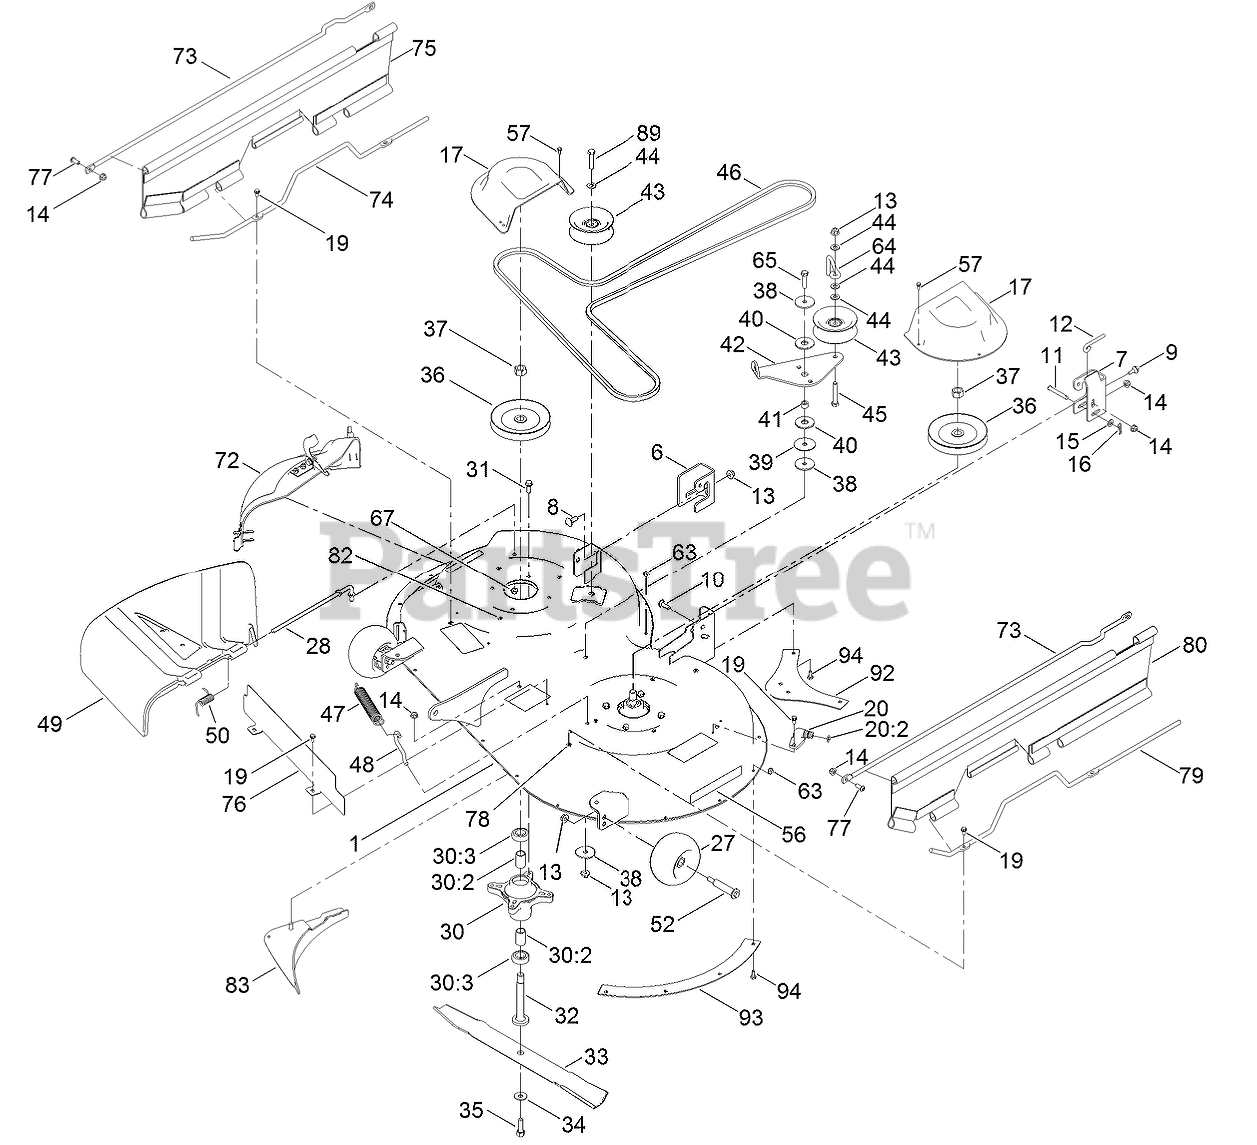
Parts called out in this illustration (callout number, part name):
1	42 INCH DECK AND DECAL ASM
6	BRACKET-HANGER, RH
7	BRACKET-HANGER, LH
8	BOLT-CARR
9	SCREW-SHOULDER,HWH
10	SCREW-CARR
11	PIN-CLEVIS
12	ROD-LEVEL, DECK
13	NUT-HF, NI
14	NUT-HF, NI
15	WASHER-PLAIN
16	PIN-COTTER
17	COVER-BELT
19	SCREW-HWH
20	FITTING-WASHOUT
20:2	O-RING
27	ROLLER-SCALP, ANTI
28	ROD-PIVOT
30	SPINDLE ASM
30:2	SPACER
30:3	BEARING-BALL
31	SCREW-TAPTITE
32	SHAFT-SPINDLE
33	BLADE-MULCH
34	WASHER-BELLEVILLE
35	SCREW-HH
36	PULLEY
37	NUT-HEX
38	WASHER-REBOUND
39	WASHER
40	WASHER-FRICTION, COMPOSITE
41	SPACER
42	ARM-IDLER
43	PULLEY-IDLER, FLAT
44	WASHER-FLAT
45	SCREW-HH
46	V-BELT
47	SPRING-EXTENSION
48	HOOK-RETURN, SPRING
49	DEFLECTOR
50	SPRING-TORSION
52	BOLT-SHOULDER
56	DECAL-RECYCLER
57	SCREW-TAPTITE
63	NUT-LOCK, NI
64	GUIDE-IDLER, BELT
65	SCREW-HH
72	42 INCH MULCH PLUG ASM
73	ROD-SUPPORT, UPPER
74	ROD-SUPPORT, LOWER (RH)
75	RIGHT GUARD ASM
76	SHIELD-FROUNT
77	SCREW-HSBH
78	NUT-RETAINING
79	ROD-SUPPORT, LOWER (LH)
80	LEFT GUARD ASM
82	NUT-RETAINING
83	BAFFLE-CLIPPING
89	SCREW-HH
92	BAFFLE-BLOWOUT, REAR
93	BAFFLE-BLOWOUT, SIDE
94	SCREW-HH
